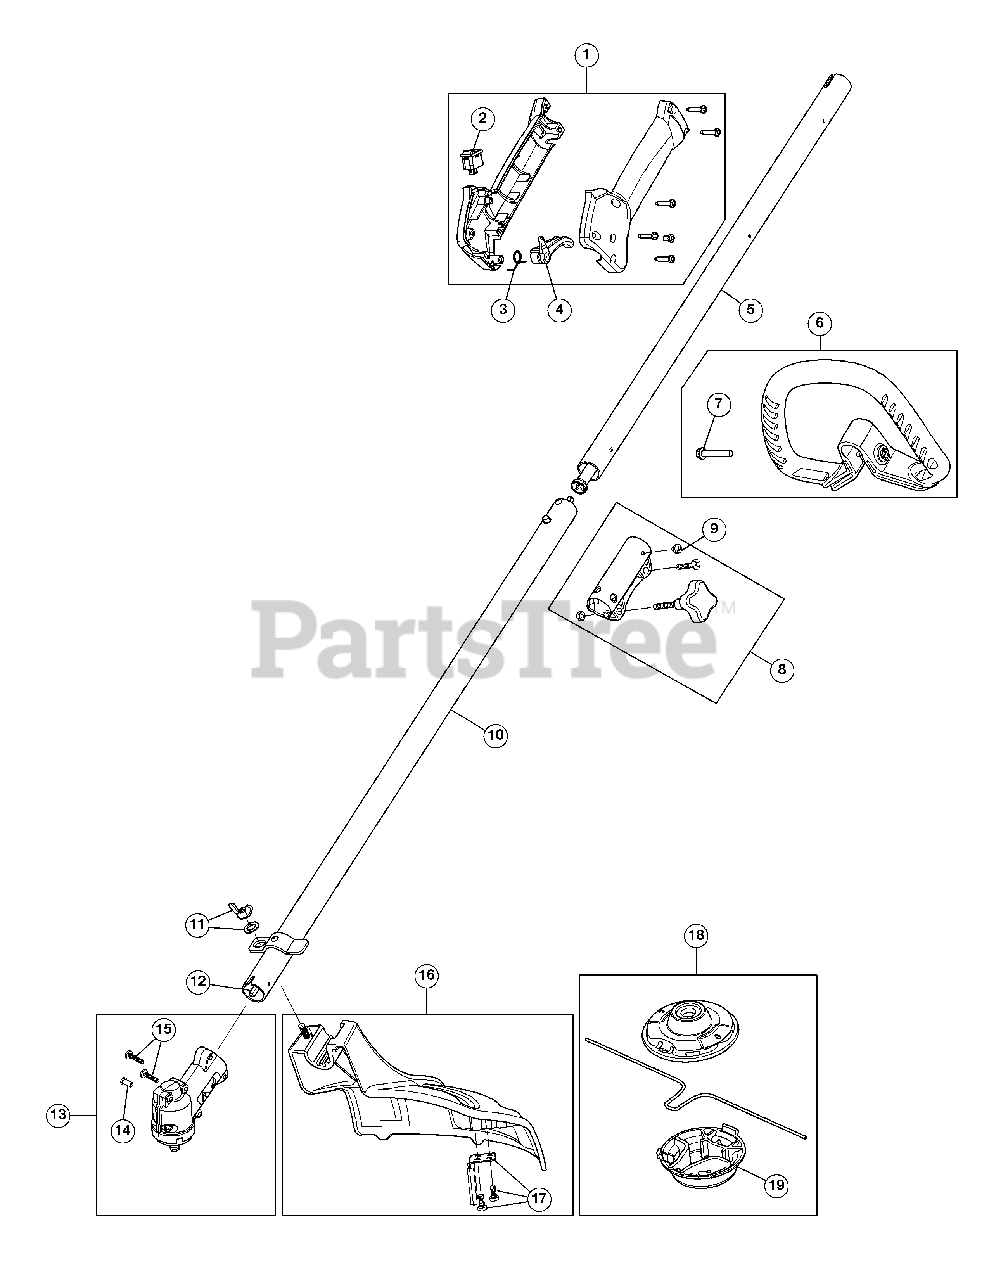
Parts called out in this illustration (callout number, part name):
1	Throttle Housing Assembly (Incl. 2 - 4)
3	Throttle Trigger Spring
4	Throttle Trigger
5	Upper Shaft Housing Assembly
6	D-Handle (Incl. 7)
7	D-Handle Bolt
8	Split Boom Coupler (Incl. 9)
9	Coupler Anti-Rotation Screw
10	Lower Shaft Housing Assembly
11	Shield Mounting Hardware
12	Lower Flexible Drive Shaft
13	Gearbox Assembly (Incl. 14 & 15)
14	Gearbox Anti-Rotation Screw
15	Gearbox Mounting Hardware
16	Shield Assembly (Incl. 11 & 17)
17	Blade Assembly
18	Cutting Head Assembly (Incl. 19)
19	Glide Cap
